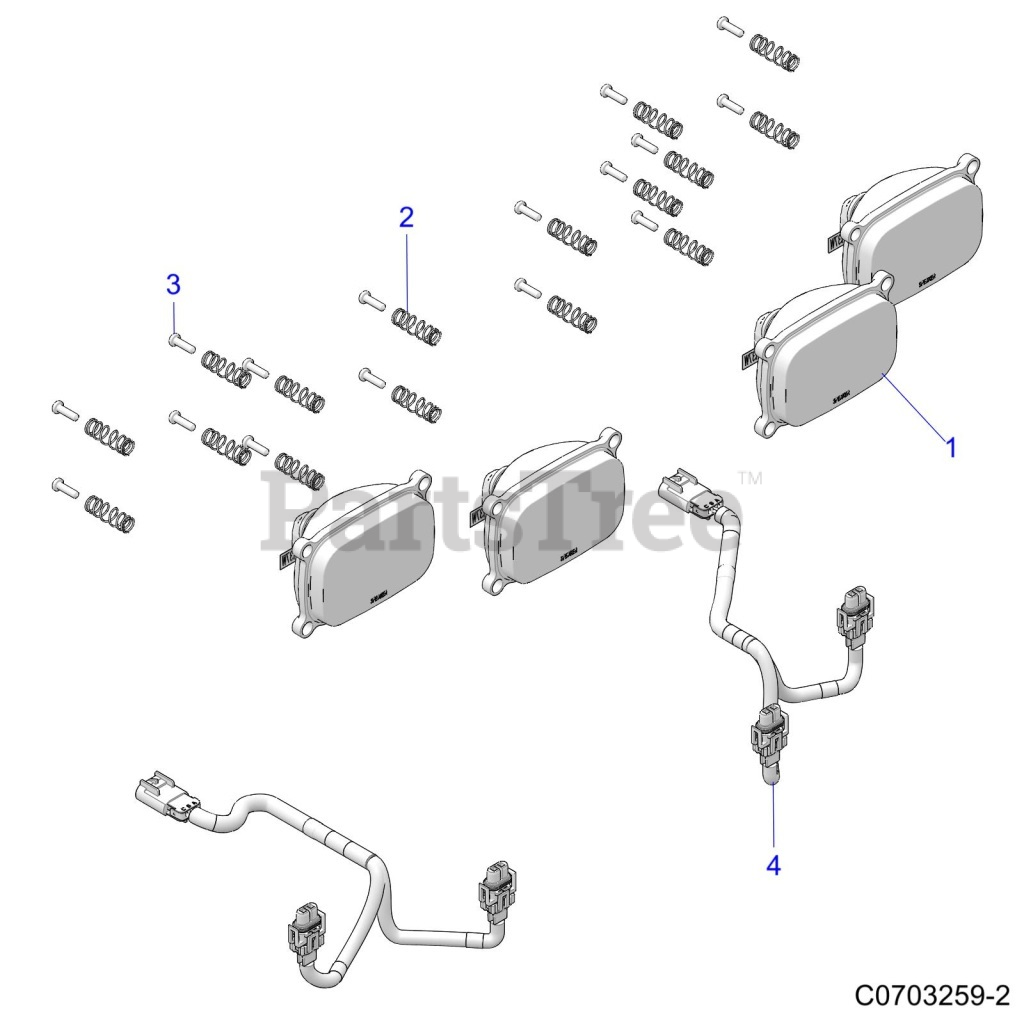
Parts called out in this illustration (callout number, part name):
1	ASM-HEADLIGHT
2	SPRING, HEADLIGHT
4	HARNESS-HEADLIGHT,ARNS
